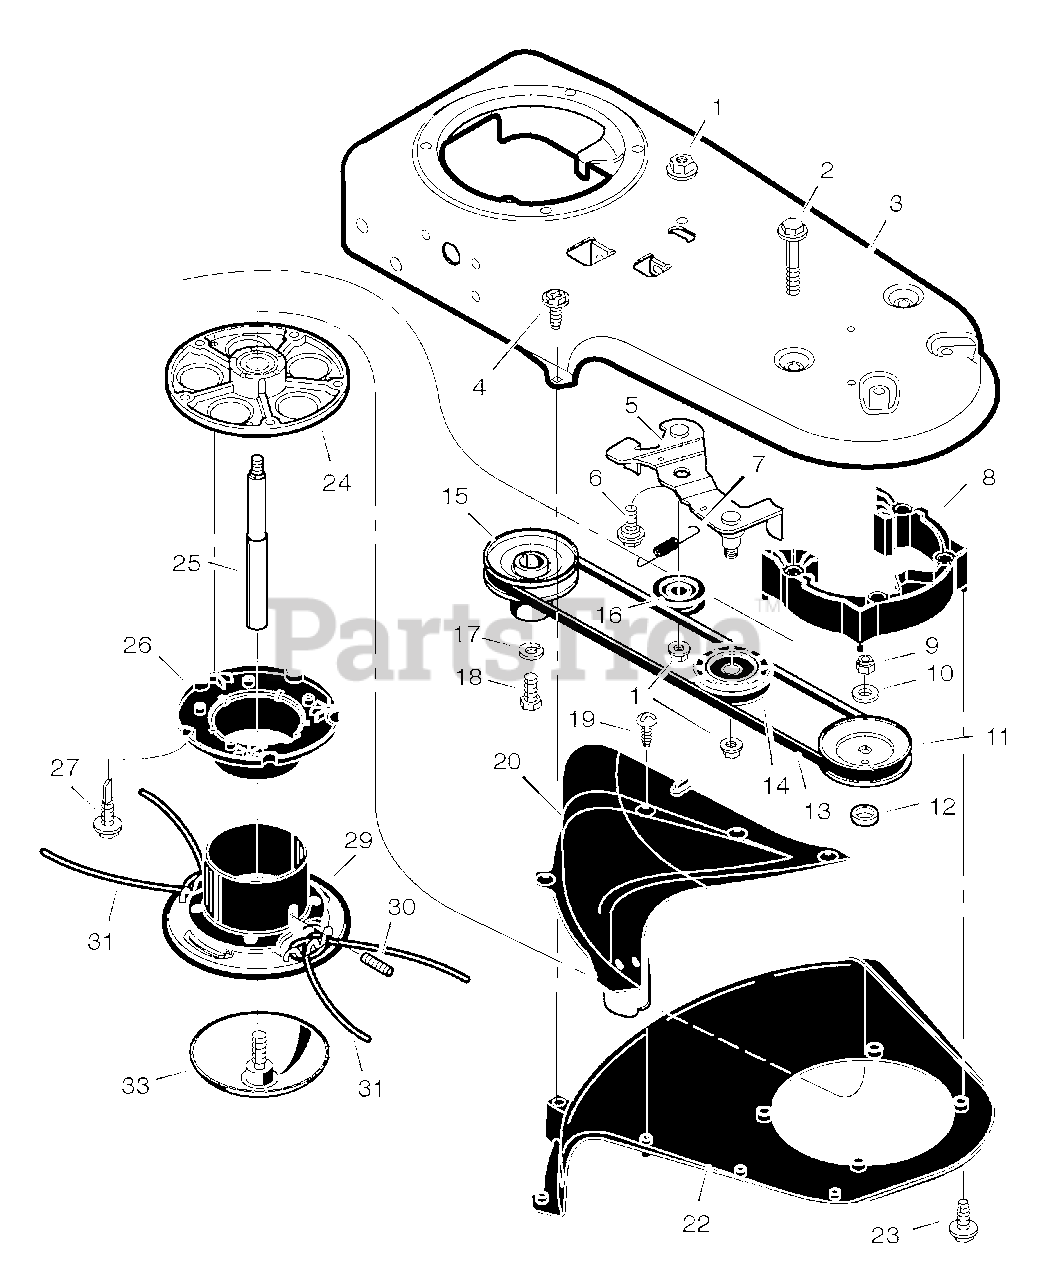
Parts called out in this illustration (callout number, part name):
3	FRAME, Trimmer
5	BRACKET, Idler Assembly
11	PULLEY, Cutting Head
14	PULLEY, Idler
15	PULLEY, Engine
16	PULLEY, Idler
17	LOCKWASHER
20	GUARD Assembly
24	JACKSHAFT HOUSING ASSEMBLY
25	Shaft, Cutting
26	WRAP, Upper Head
29	ASSEMBLY, Cutting Disc
30	SCREW, Set
31	LINE, Cutting
33	GUIDE Assembly, Metal Height
